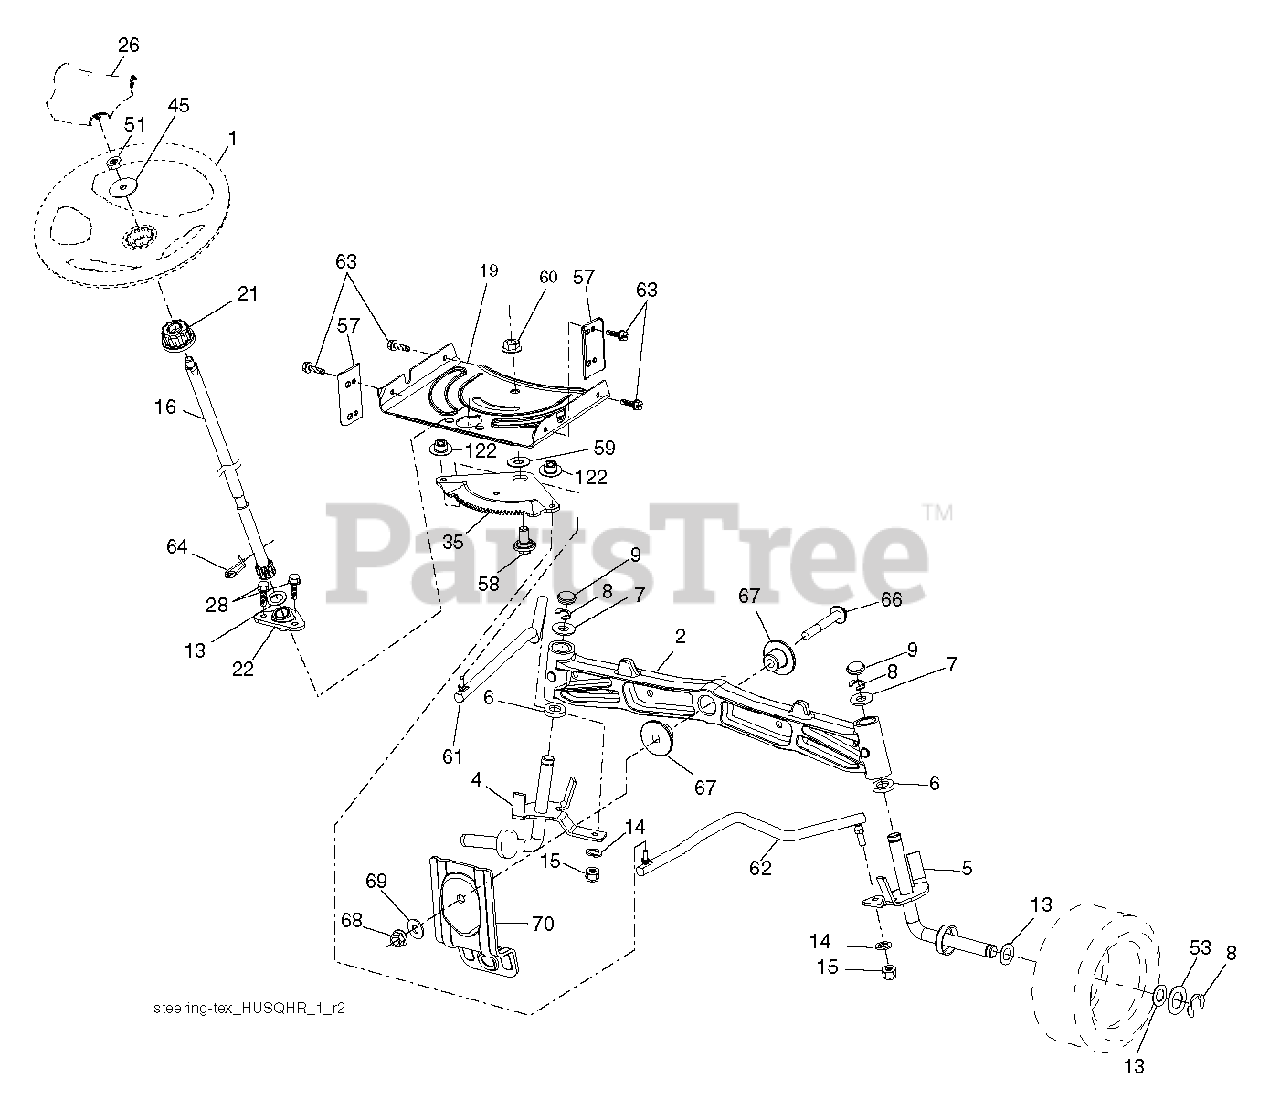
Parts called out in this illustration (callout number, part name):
1	WHEEL.STEERING.HUSQ.PREM.HRDRM
2	AXLE.CAST.IRON
4	SPINDLE.WELDED.LH.15"TEX
5	SPINDLE.WELDED.RH.15"T
6	THRUST WASHER
9	CAP.SPINDLE.BLACK
14	WASHER, LOCK 3/8
15	NUT CROWNLOCK 3/8-24
16	SHAFT, STEERING
19	PLATE.STEER.DDL.NLT/NG
21	ADAPTER, WHEEL STNG..
22	STEERING.SUPT.LOWER.
26	INSERT.CAP.WHL.STRG.HUSQ.PREM
28	SCREW, 3/8-16X3/4
35	GEAR.SECTOR.PLATE.DDL.
45	WASHER 9/16"ID, 2 3/8"OD
51	NUT.HEX.1/2-20
53	WASHER.HARDENED
57	BRACKET.UPSTOP.TEX
58	BOLT.SHOULDER.SECTOR.P
59	WASHER.THURST.SECTOR.S
60	NUT FLANGE LOCK 5/8-11
61	DRAGLINK.LH.BALLSTUD.D
62	DRAGLINK.RH.BALLSTUD.D
63	SCREW
64	RETAINER.CLIP.SPRING.S
66	BOLT HEX FGHD 7/16-14 X 3 SERR
67	BUSHING.PM.FRONT AXLE
68	NUT.LOCK.FLANGE.7/16
69	WASHER.1.5X.505X.118
70	BRKT.DECK.SUSPENSION.F
122	CAP.GEAR.SECTOR.TEX
